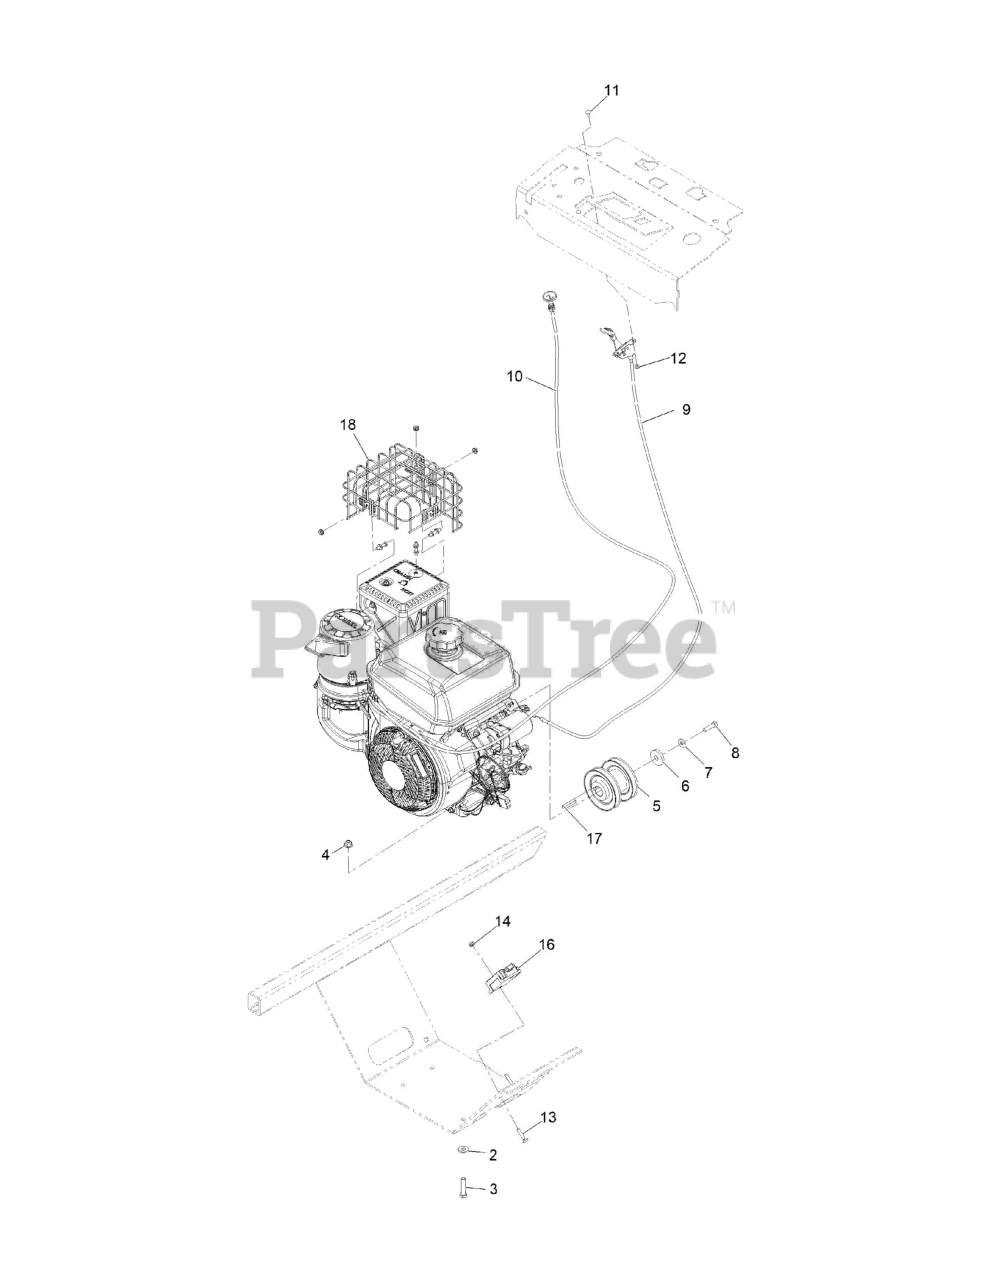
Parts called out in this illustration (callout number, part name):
2	WASHER-BELLEVILLE
3	SCREW-HH
4	NUT-HF, NI
6	WASHER-CLUTCH
7	WASHER-SPRING
8	SCREW-HH
9	CONTROL-THROTTLE
10	CABLE-CHOKE, PUSH/PULL
11	BOLT-CARR
12	NUT-LOCK, NI
13	SCREW-CARR
16	REGULATOR
17	KEY-SQUARE, 7MM
18	KIT-MUFFLER BIRDCAGE
